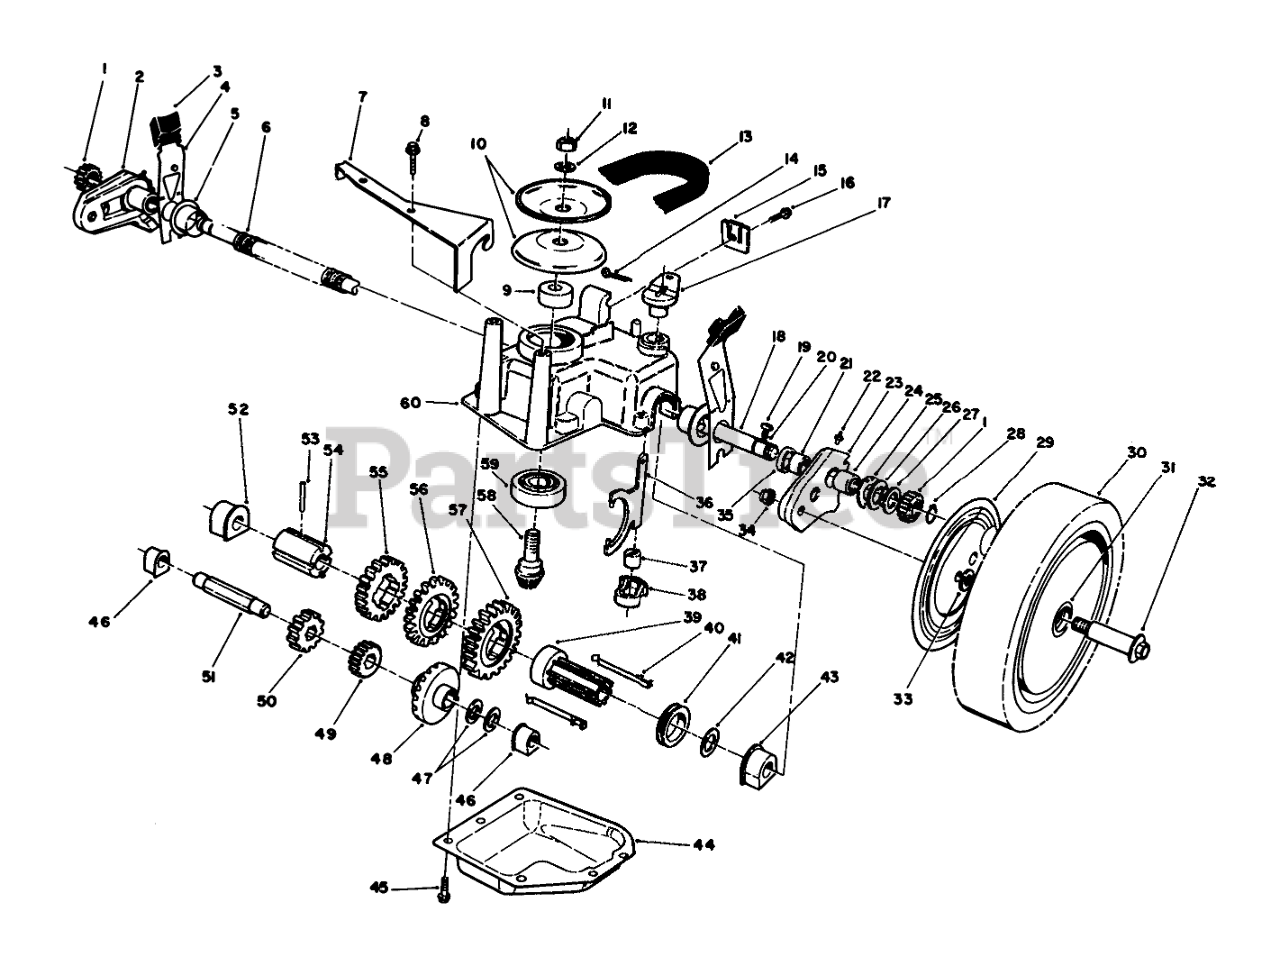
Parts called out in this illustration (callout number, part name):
1	GEAR-PINION
2	Pivot Arm Assembly-R.H. (Incl. Ref. #21, 22, 24 & 35)
3	KNOB-ARM
4	SPRING ARM ASM SP
5	CAP-END
6	CONDUIT-CONVOLUTED, SPLIT
7	Bracket-Guide
8	SCREW-HWHTF
10	Pulley Half
11	NUT-HEX
12	WASHER-FLAT
13	V-BELT E
14	PIN-COTTER
15	Cable Clamp
16	SCREW-HWHTF
17	SHIFT LEVER
18	Output Shaft
19	KEY RECTANGULAR
20	SPRING-COMPRESSION
21	BUSHING
22	FITTING-GREASE
23	Pivot Arm Assembly-L.H. (Incl. Ref. #21, 22, 24 & 35)
24	BEARING-ROLLER
25	INNER THRUST WASHER
26	WASHER-THRUST, OUTER
27	WASHER-THRUST, OUTER
28	PIN-ROLL
29	WHEEL COVER
30	Wheel-Tire & Gear Assy. (Incl. Ref. #31)
31	BUSHING
32	WHEEL BOLT
33	WASHER
34	Nut
35	SEAL-OIL
36	YOKE-SHIFT
37	BUSHING-YOKE
38	RETAINER-FORK, SHIFT
39	Sleeve-Shift Key
40	Key Shift
41	SHIFT COLLAR
42	Washer
43	BUSHING-OUTPUT
44	Cover-Gearcase
45	SCREW-HWHTF
46	BUSHING
47	Washer-Thrust
48	Gear-Bevel
49	PINION-20T
50	PINION-25T
51	SHAFT-INTERMEDIATE
52	BUSHING
53	PIN-SPRING
54	SLEEVE-GEAR
55	GEAR-39T
56	GEAR-44T
57	GEAR-49T
58	Gear-Pinion
59	BEARING-BALL
60	CASE-GEAR, UPPER
